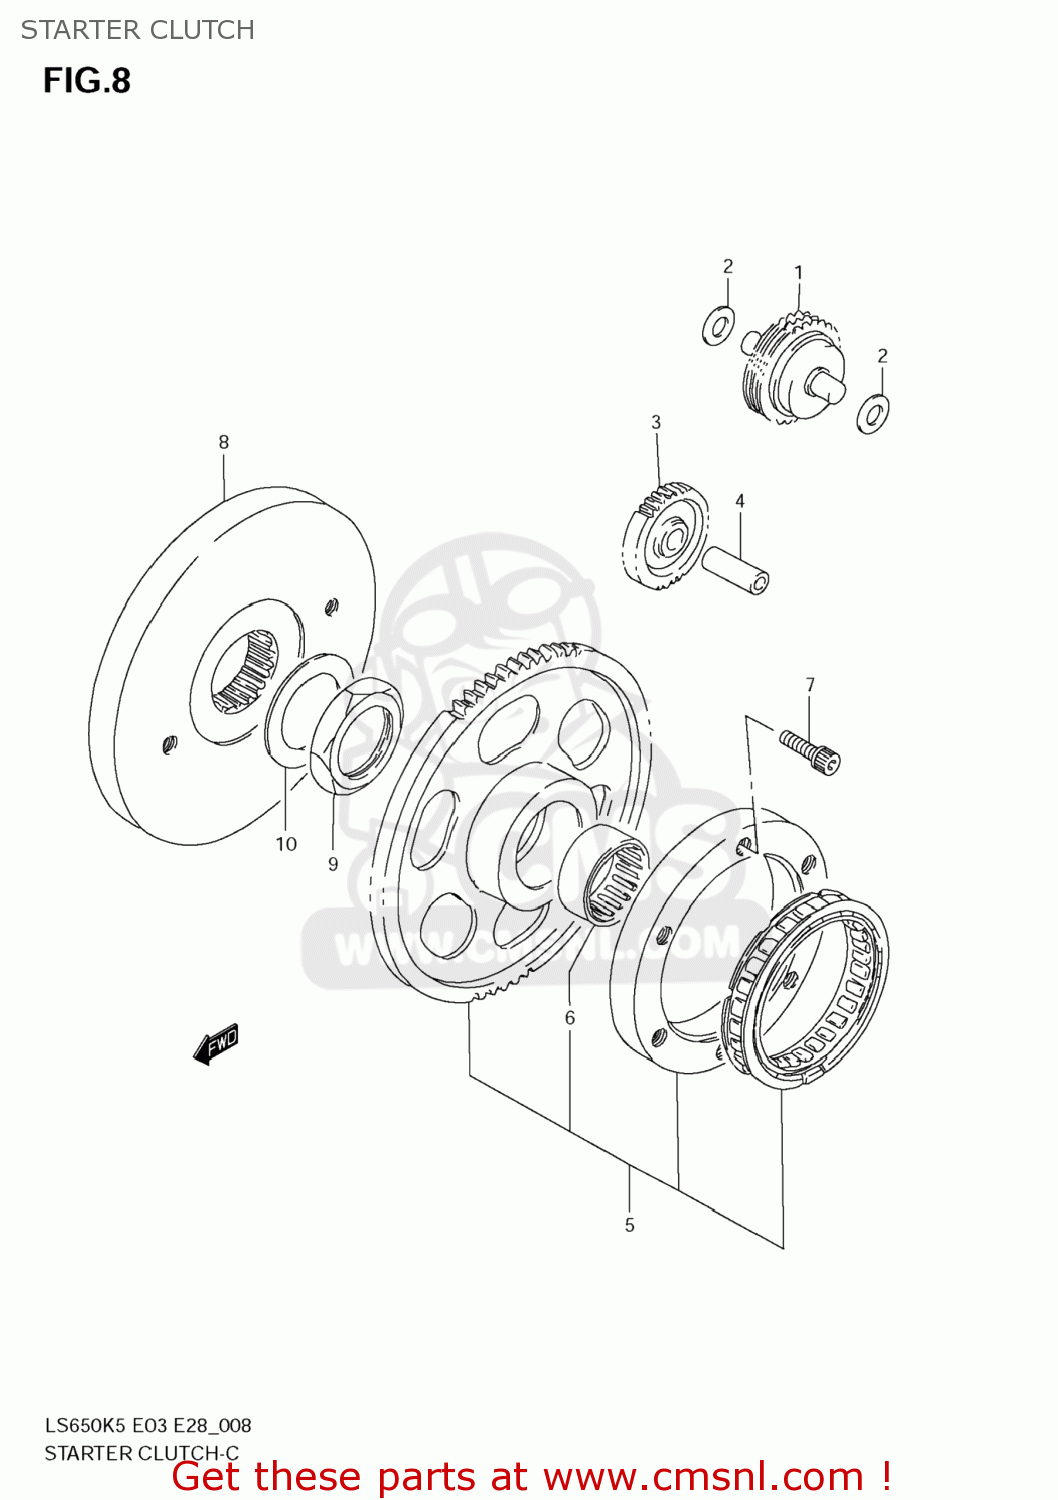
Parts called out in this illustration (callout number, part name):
1	LIMITER ASSEMBLY,STARTER IDLER GEAR N
2	SHIM(10X18X1)
3	GEAR,STARTER IDLE NO.2
4	PIN(10X30)
5	CLUTCH SET,STARTER
6	BEARING(31X39X17.8)
7	BOLT(8X16)
8	FLYWHEEL
9	NUT,FLYWHEEL
10	WASHER
